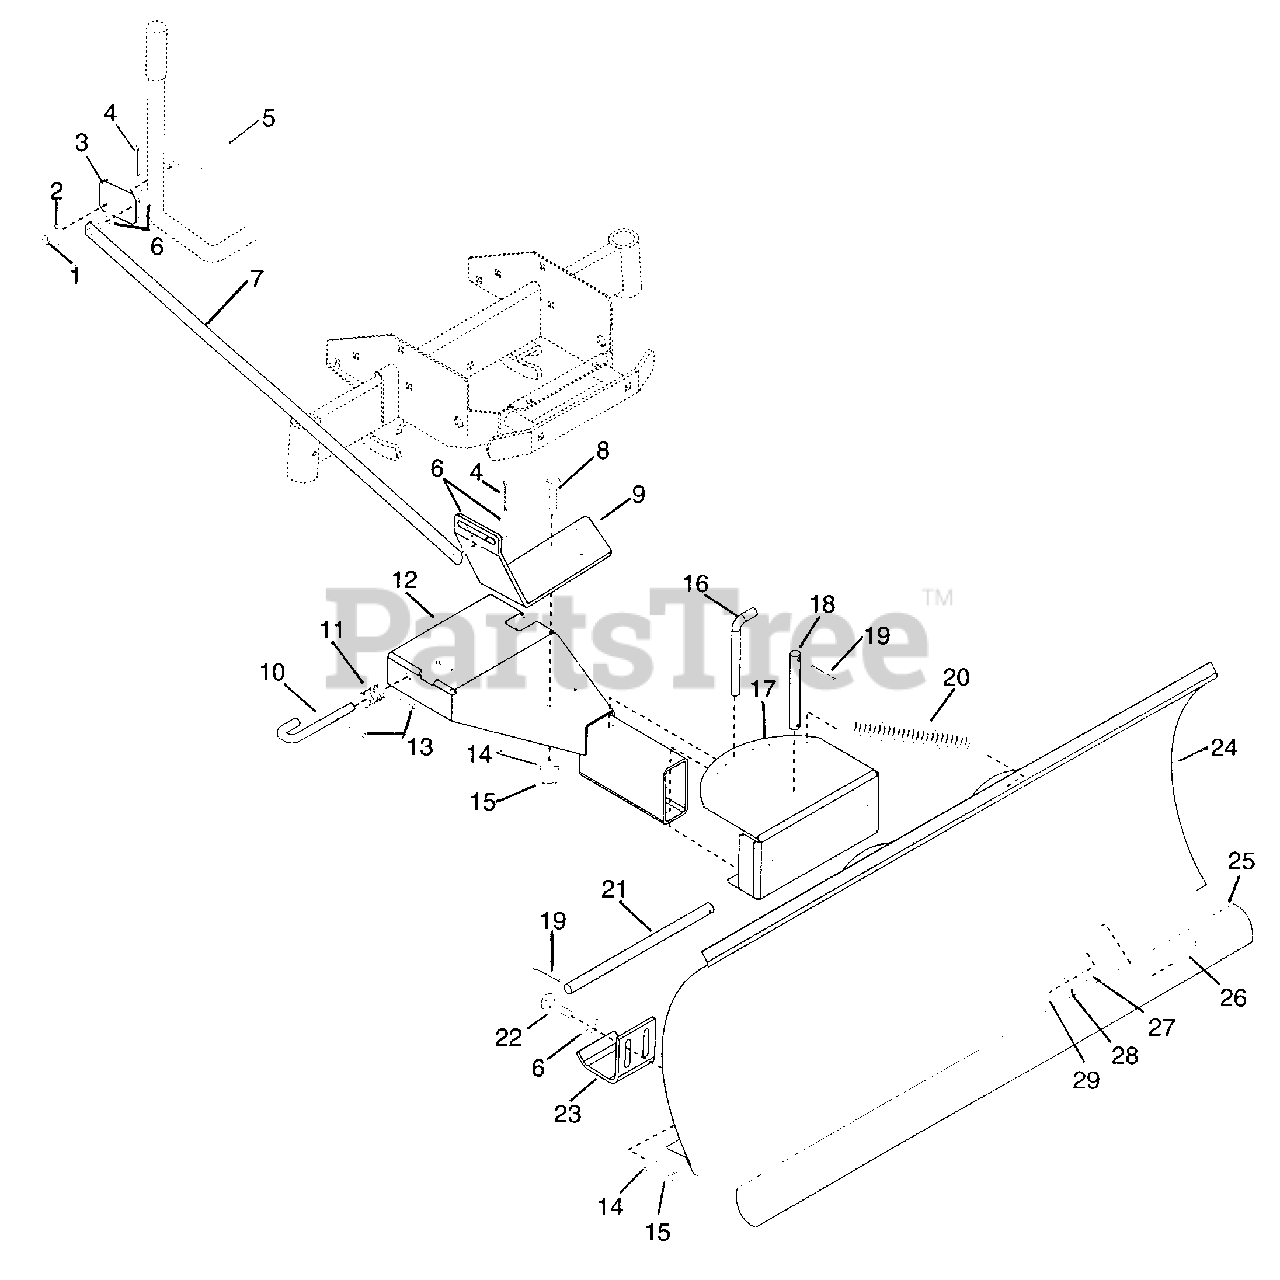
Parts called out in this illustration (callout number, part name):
1	NUT-HEX .250-20 PL
2	WSHR-LK .250X.077 HVY PL
3	LIFT HANDLE PLATE
4	PIN-COTR .12X.75 PL
6	WSHR-FL-STL .438X1.0X.083 PL
7	LIFT STRAP
8	BLT-HEX .38-16X1.00 PL GR5
9	LIFT BRACE
10	LATCH PIN
11	SPRG, COMP .058X.65X2.13 WLD15
13	PIN-ROLL .125X.75
14	WSHR-LK .375X.094 MED PL
15	NUT-HEX .375-16
17	FRONT BLADE POSITIONER
19	PIN-COTR .18X1.0 PL
20	SG-TENS .187X1.50X9.94 WLD 40
22	BLT-RDHDSQNK .38-16X1.0 PL
23	SKID SHOE
24	WELDMENT, SNOW BLADE
25	WEAR PLATE
26	BLT-RDHDSQNK .31-18X1.00 PL
27	WSHR-FL-STL .38X.875X.083 PL
28	WSHR-LK .312X.097 PL HVY
29	NUT-HEX .312-18
